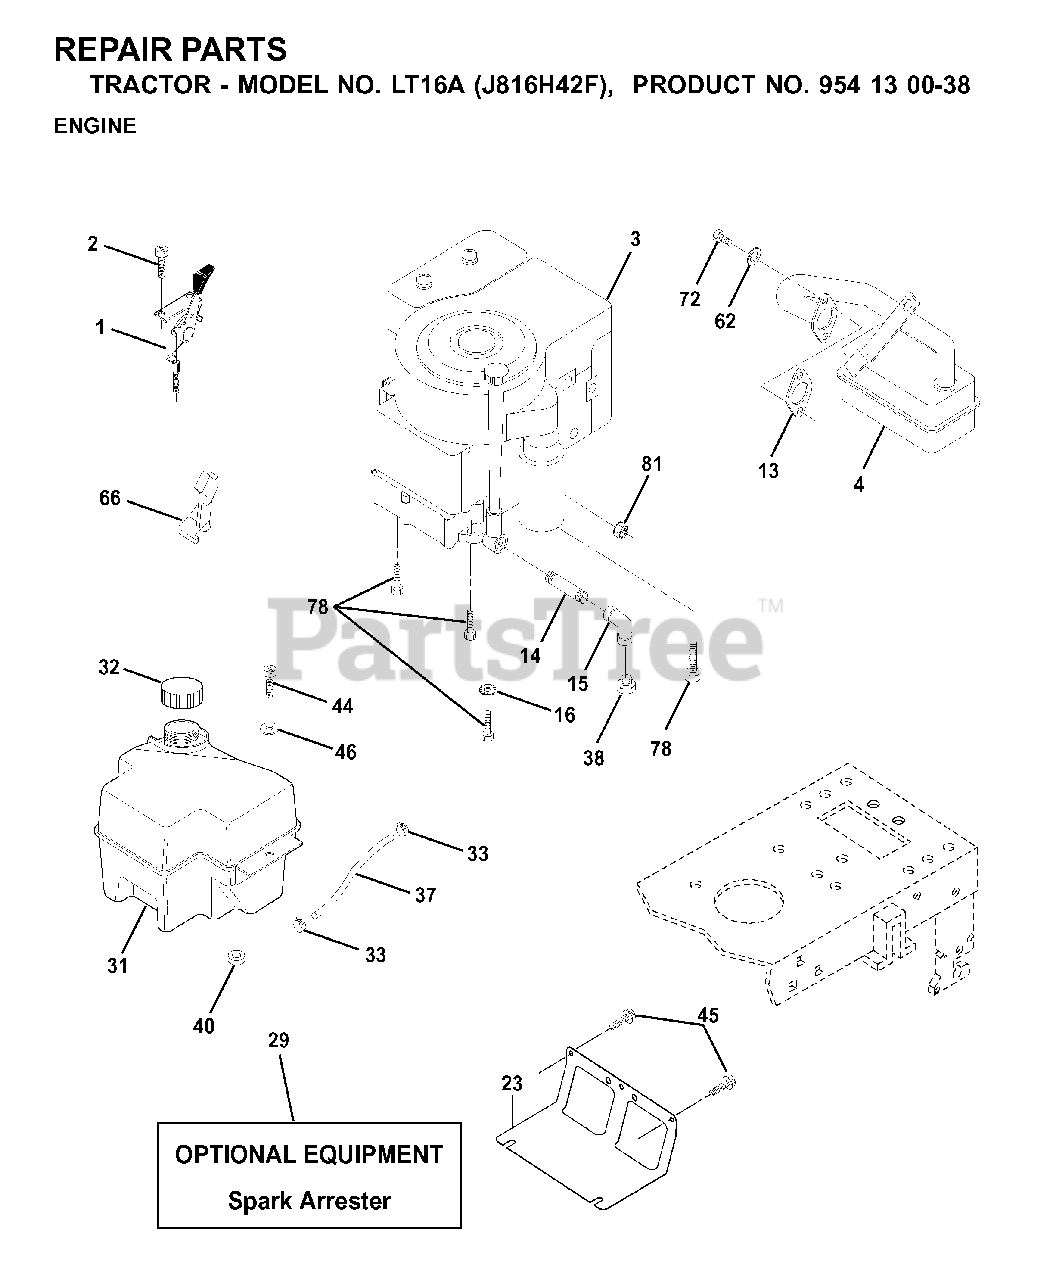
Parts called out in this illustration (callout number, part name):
1	CONTROL
2	SCREW LT
13	REPL BY 532 27 22-93
15	ELBOW
16	LOCKWASHER
23	SHEILD.BROWNING.DBR.GUARD
29	ARRESTER SPARK (OPTIONAL)
31	FUEL TANK
32	FUEL CAP
33	HOSE CLAMP
37	LINE.FUEL.20
40	GROMMET T
44	SCREW HEX CRT
45	SCREW 3/8-16X3/4
62	LOCKWASHER
66	STOP THROTTLE
72	SCREW
78	SCREW.3/8-16
81	NUT FLANGE 1/4-20 STARTER NUT
